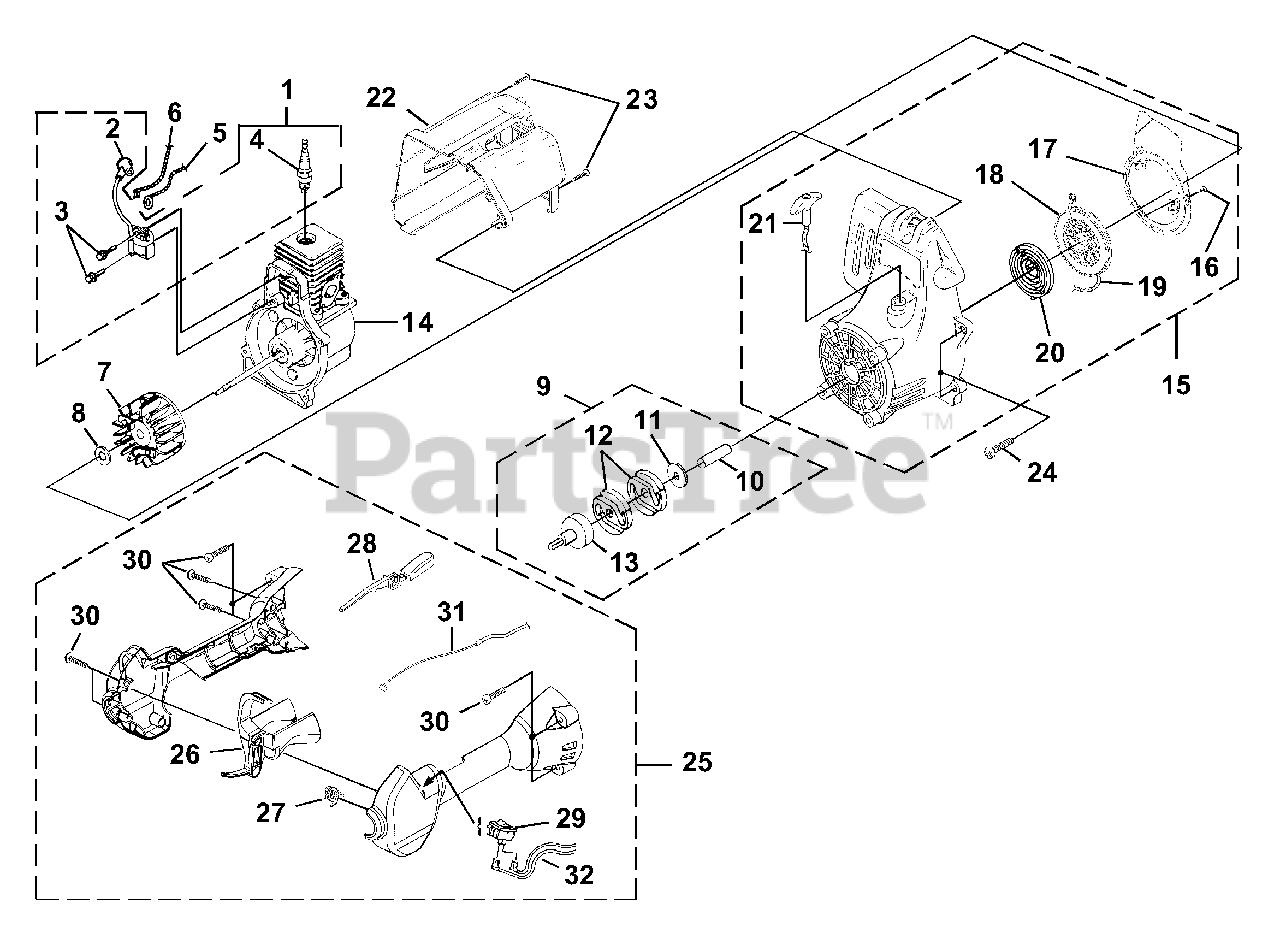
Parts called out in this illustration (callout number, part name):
1	IGNITION KIT
2	TERMINAL & COVER
3	SCREW-Taptite (8-32 X 1")
4	SPARK PLUG
5	LEAD-Electrical
6	LEAD-Electrical
7	ROTOR KIT
8	WASHER-Flat
9	CLUTCH AND DRUM KIT
10	SPACER
11	WASHER-Flat
12	CLUTCH
13	CONNECTOR AND DRUM
14	SHORT BLOCK
15	STARTER ASSEMBLY
16	SCREW-Thread Form (8-16 X 1/2")
17	BAFFLE-Air
18	PULLEY-Starter
19	ROPE-Starter (42")
20	SPRING & CONTAINER
21	GRIP-Starter (Yellow)
22	HOUSING-Rear Kit
23	SCREW-Plastite (10-14 X 3/4")
24	SCREW-Taptite (10-24 X 3/4")
25	CONTROL HANDLE ASSY.
26	TRIGGER-Throttle
27	SPRING
28	THROTTLE INTERLOCK
29	SWITCH
30	SCREW-Taptite (10-14 X 1")
31	CABLE-Throttle
32	LEAD-Electrical
